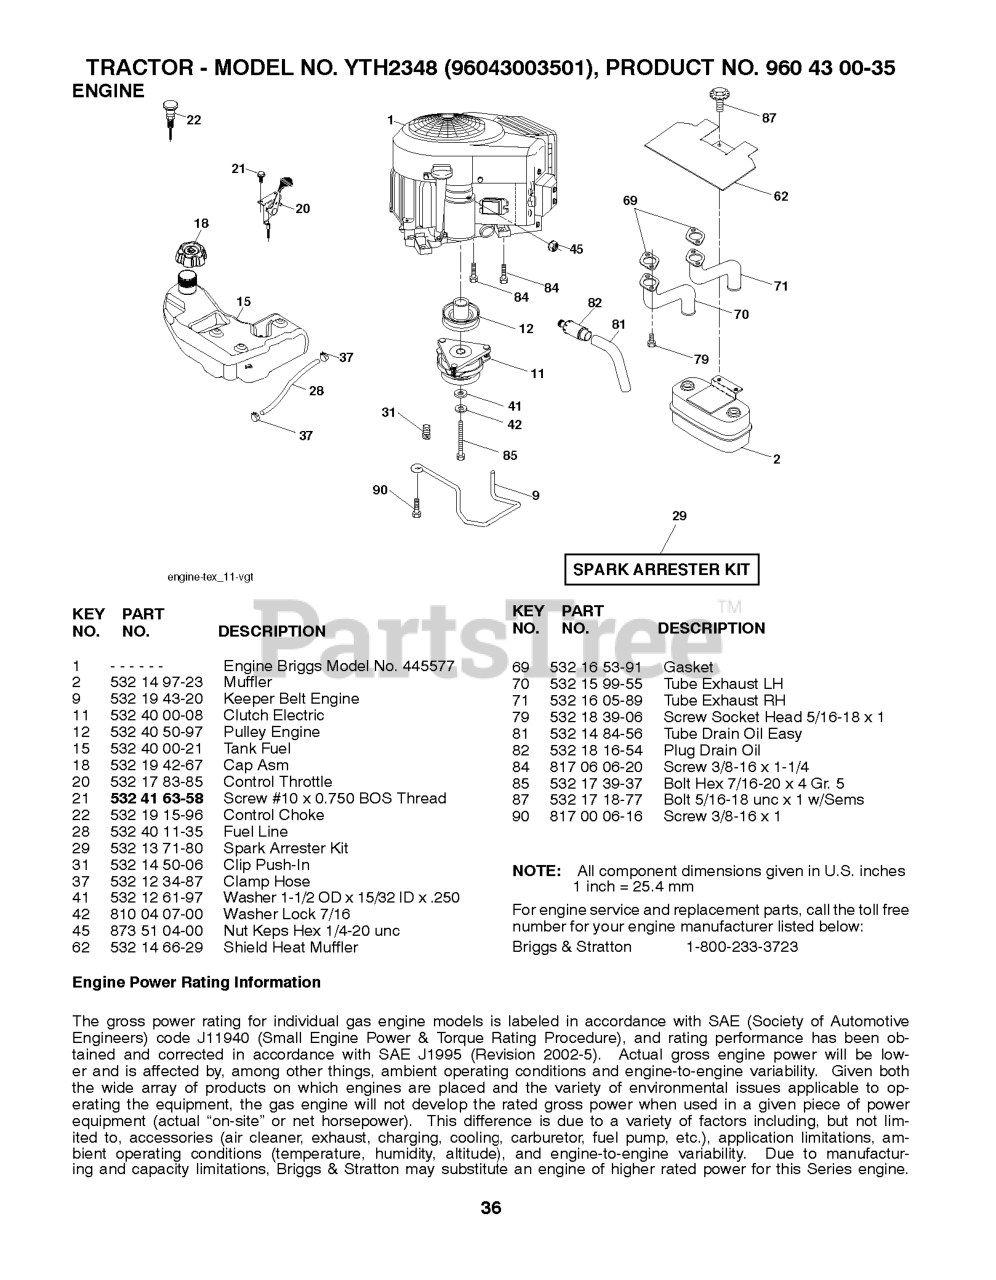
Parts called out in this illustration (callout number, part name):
2	MUFFLER.TWIN.CYL.LOW.TONE
9	KEEPER.BELT.ENGINE.4.2
11	CLUTCH.ELECTRIC.LT.48"*
12	PULLEY.ENGINE.TUFFTORQ
15	TANK.FUEL.SIDE-FILL.3.NON-EPA
18	CAP.FUEL.TANK.3"GREY
20	THROTTLE CABLE
21	SCREW.#10 X 0.750.BOS
22	CONTROL.CHOKE.ERGO.PUSH-IN.BLA
28	LINE.FUEL.64"REAR.EMIS
29	KIT.SPARK ARRESTOR 794945 B&S
37	HOSE CLAMP
42	LOCKWASHER
45	NUT
62	RP SHIELD HEAT MUFFLER
69	GASKET.MUFFLER
70	RP.EXHAUST.TUBE.LH.BS/TWIN
71	EXHAUST.TUBE.RH.BS/TWIN
79	SCREW.SOCKET.HEAD.5/16-18
81	TUBE, DRAIN OIL ASM.
82	PLUG DRAIN OIL EASY
84	SCREW.3/8-16
85	BOLT HEX 7/16-20X4-1/4"
87	BOLT.5/16-18UNCX3/4 W/SEMS.BLK
90	SCREW 3/8-16X1
